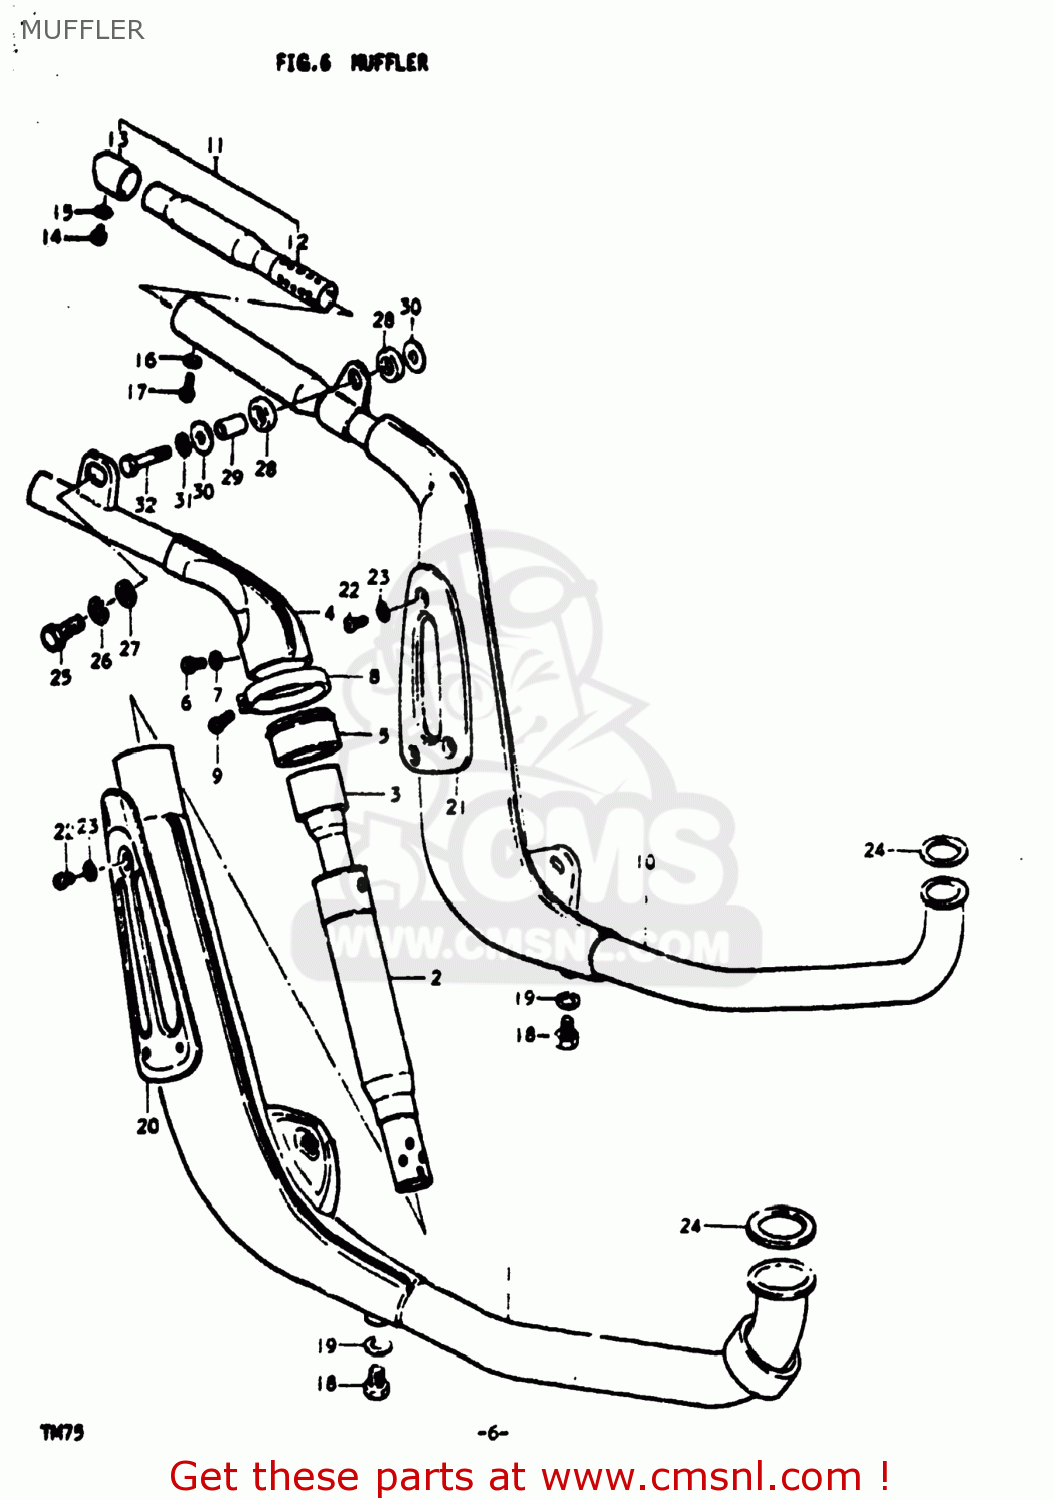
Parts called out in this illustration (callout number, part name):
1	MUFFLER ASSEMBLY
2	ARRESTER,SPARK
3	TUBE,MUFFLER CLEAN OUT
4	EXHAUST EXTENSION
5	GASKET,MUFFLER TAIL PIPE (NAS)
6	SCREW(6X12)
7	GASKET
8	CLAMP
9	SCREW
10	MUFFLER ASSEMBLY
12	TUBE,CLEAN OUT
13	CUTTER,SPARK ARRESTER
14	SCREW
15	LOCK WASHER
16	GASKET 6.2X12X1.5 (MCA)
17	SCREW
18	BOLT 10X9
19	GASKET(10X14X3.6) (NAS)
20	COVER,MUFFLER
21	COVER,MUFFLER
22	SCREW
23	LOCK WASHER
24	GASKET,EXHAUST PIPE (NAS)
25	BOLT 10X20
26	LOCK WASHER
27	WASHER
28	CUSHION
29	SPACER (10.6X17X11)
30	WASHER
31	LOCK WASHER
32	BOLT 10X25
